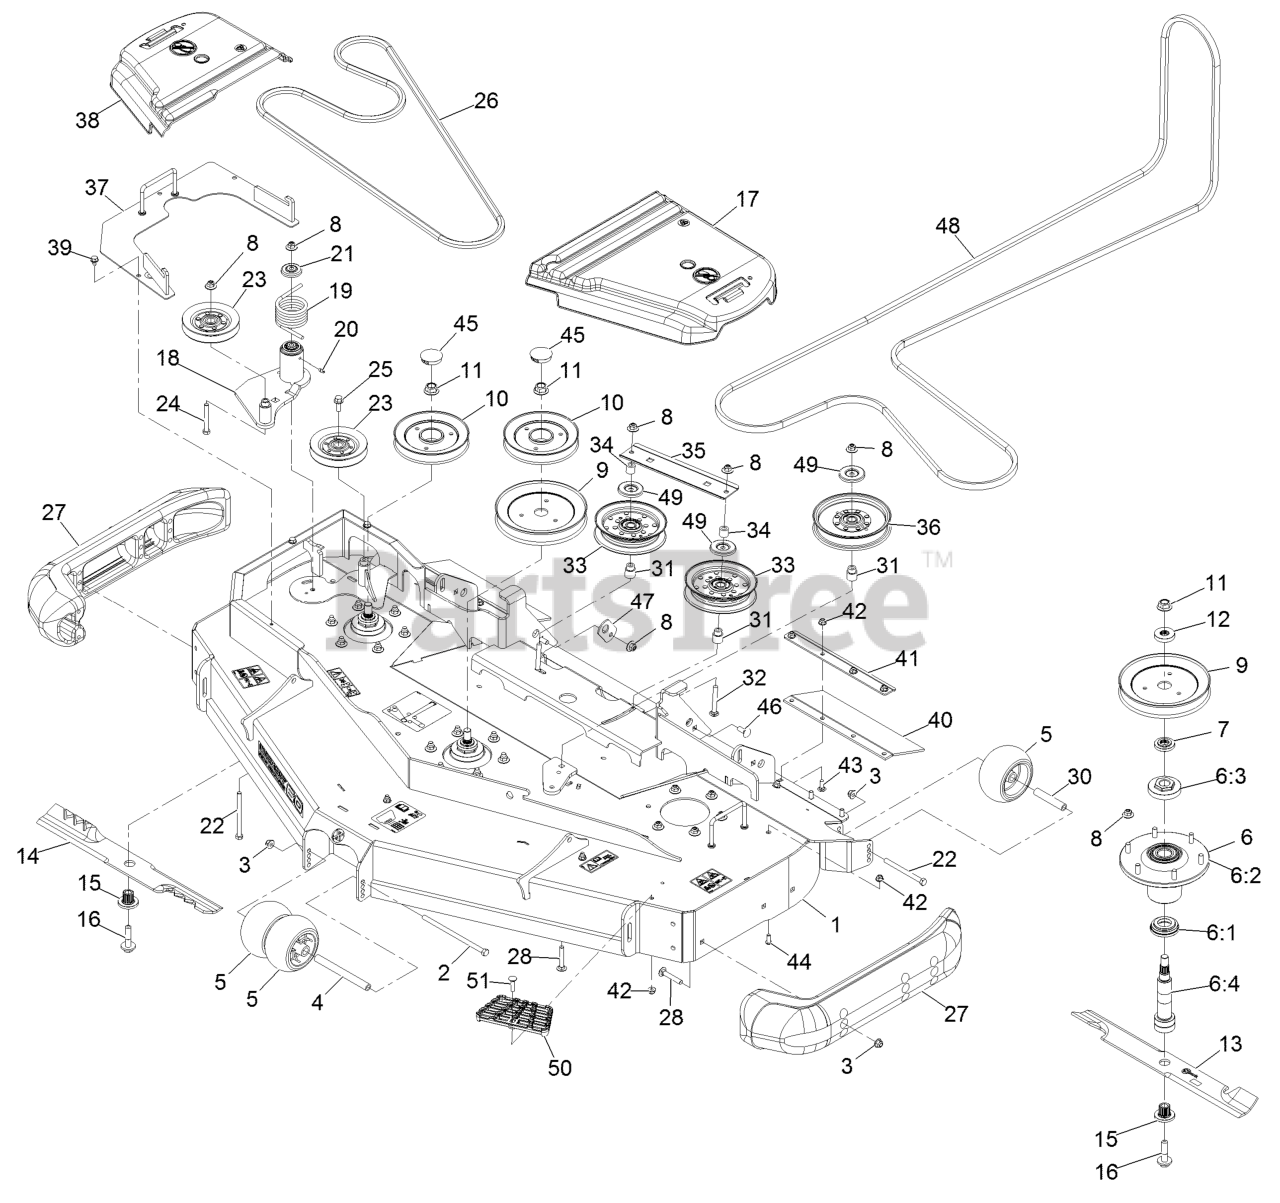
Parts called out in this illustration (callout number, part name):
1	DECK-RD60, W/DECALS
2	SCREW-HH
3	NUT-HF, NI
4	SPACER-WHEEL
5	ROLLER-SCALP, ANTI
6	ASM,SPINDLE HOUSING
6:1	GUARD,BOTTOM
6:2	ASM,CUTTER HOUSING
6:3	NUT, SPINDLE 7/8-14
6:4	SPINDLE,DOUBLE SPLINE
7	SPACER,SPLINED STEPPED
8	Nut-Nyloc 3/8-16 Flg
9	SHEAVE,BLADE DRIVE 7.25
10	SHEAVE-RD, REVERSE DRIVE
11	NUT-FLANGE, CENTERLOCK
12	SPACER,SPLINED
13	Blade-Extreme 2, 20.50"
14	Blade-Low Lift 20.5, Rd60
14	Blade-Extreme 2-20.50, Rd60
15	BUSHING,SPLINED
16	SCREW,SEMS 1/2-20 X 2.19
17	COVER-BELT, LH
18	IDLER ASM
19	SPRING-TORSION
20	FITTING-GREASE
21	GUARD-TOP
22	SCREW-HH
24	SCREW-HH
25	SCREW-HHF
26	BELT
27	SKID-BUMPER, DECK
28	Bolt-Carriage 3/8-16 X 2 1/4
30	TUBE-SPANNER
31	BUSHING-IDLER
32	SCREW-CARR
33	IDLER-PULLEY, FLAT
35	GUIDE-RD BELT
36	IDLER-PULLEY, FLAT 6.00X1
37	COVER-DRIVE REVERSE
38	COVER-BELT, RH
40	GUARD-TIRE
41	SUPPORT-OUTER FLAP
42	NUT-HF, NI
43	SCREW-CARR
44	SCREW-HSBH
45	PLUG,BLACK NYLON 1.75
46	BOLT-CARR
47	PLATE,DECK STRUT
48	BELT-V
49	SHIELD-DUST
50	STEP-DECK
51	Bolt-Carriage 5/16-18 X 1 1/4
